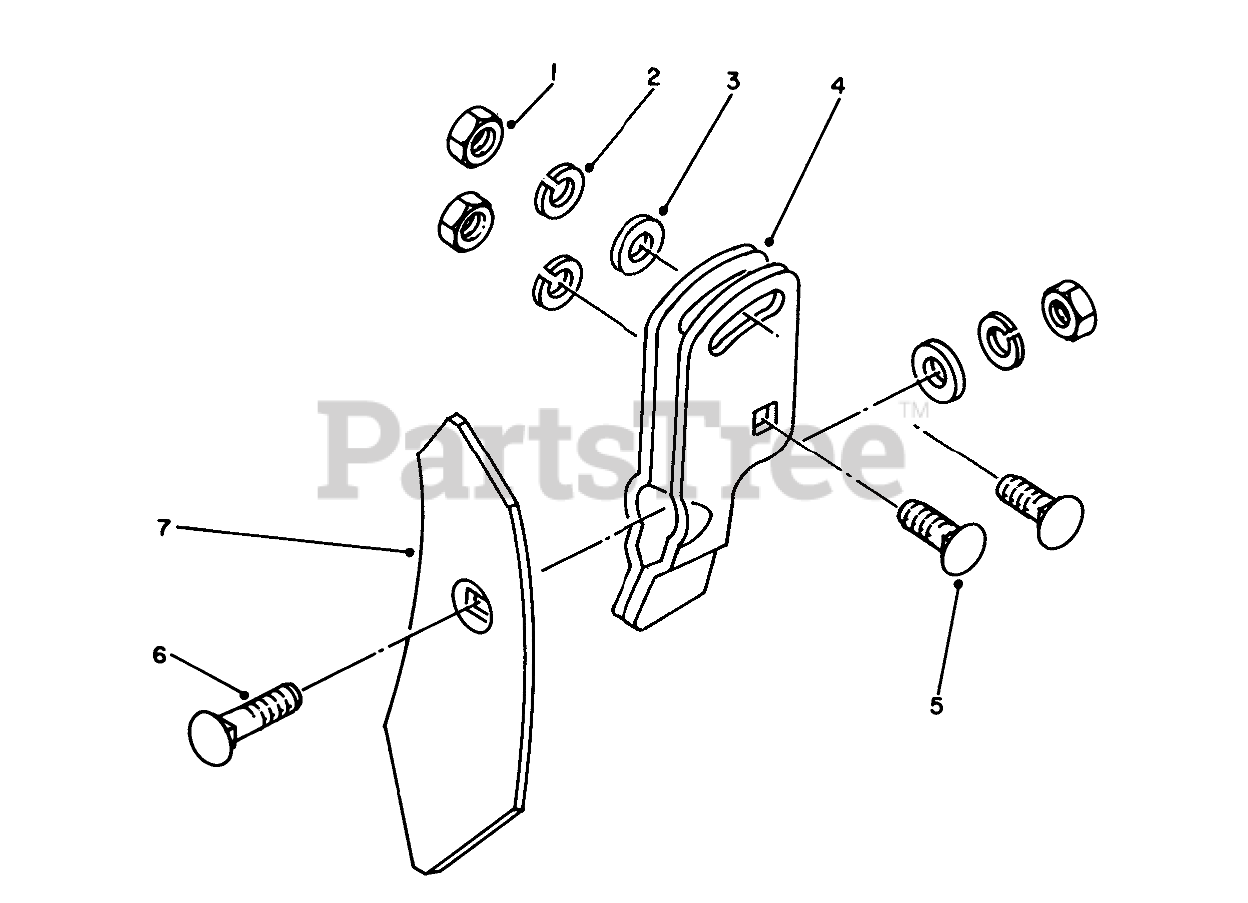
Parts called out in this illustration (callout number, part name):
1	NUT-HEX
2	WASHER-LOCK
3	WASHER-FLAT
4	Holder
5	BOLT-CARR
6	Plow Bolt
7	Shovel
